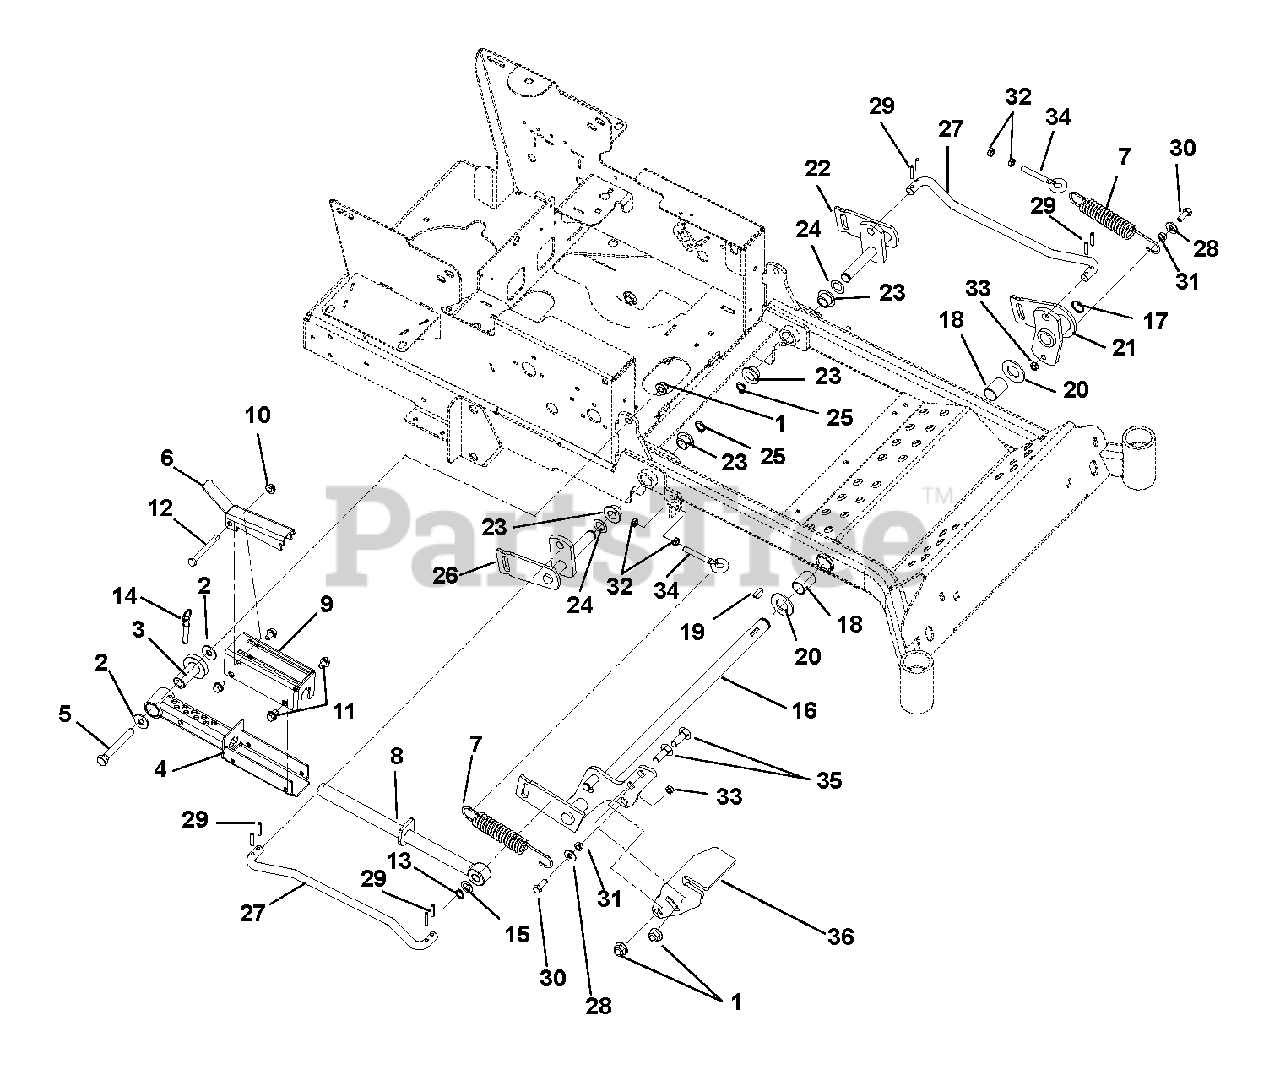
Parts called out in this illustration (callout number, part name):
1	Nut, Nyloc Top Flange .50-13
2	Washer, Flat Steel .531 x 1.25 x .10
3	Bearing, Pedestal
4	Weldment, Mechanical Lift
5	Bolt, Hex .50-13 x 3.75 Grade 5
6	Lock, Up, Mechanical Lift
7	Spring, Tension .162 x 1.25 x 8.25 WLD 25
8	Weldment, Mechanical Lift Shaft
9	Weldment, Mechanical Lift Cover
10	Nut, Nyloc Flange 3/8-16
11	Screw, Tapping .38-16 x .50 Hex Washer Head
12	Bolt, Hex .38-16 x 3.25 Grade 5
13	Ring, Retaining External .625 x .050
14	Pin, Spring Ball .375 O.D. x 1.50
15	Washer, Flat Steel .630 x 1.005 x .062
16	Deck Lift
17	Ring, Retaining External 1.00 x .078
18	Bushing 1.00 ID x 1.125 OD x 1.50
19	Key, Woodruff .25 x 1.00
20	Washer, Flat Steel 1.062 x 2.0 x .134
21	Weldment, Left Hand Mower Lift Arm
22	Weldment, Left Hand Rear Mower Lift Arm
23	Bushing, Flange Nylon .762 x 1.0 x .580 x 1.48
24	Washer, Hardened Steel .758 x 1.23 x .031
25	Ring, Retaining External .689 x .077
26	Weldment, Right Hand Rear Mower Lift Arm
27	Rod, Lift Assist
28	Washer, Flat Steel .438 x 1.00 x .083
29	Pin, Roll .25 x 1.25 Stainless Steel
30	Bolt, Hex .38-16 x 1.00 Grade 5
31	Bushing, Sleeve .377 x .624 x .235
32	Nut, Hex, Jam .375-16
33	Nut, Locking Jam Center .375-16
34	Bolt, Eye .375-16 x 2.50
35	Bolt, Round Head Square Neck .50-13 x 1.50 Grade 5 YZ
36	Foot Pedal
